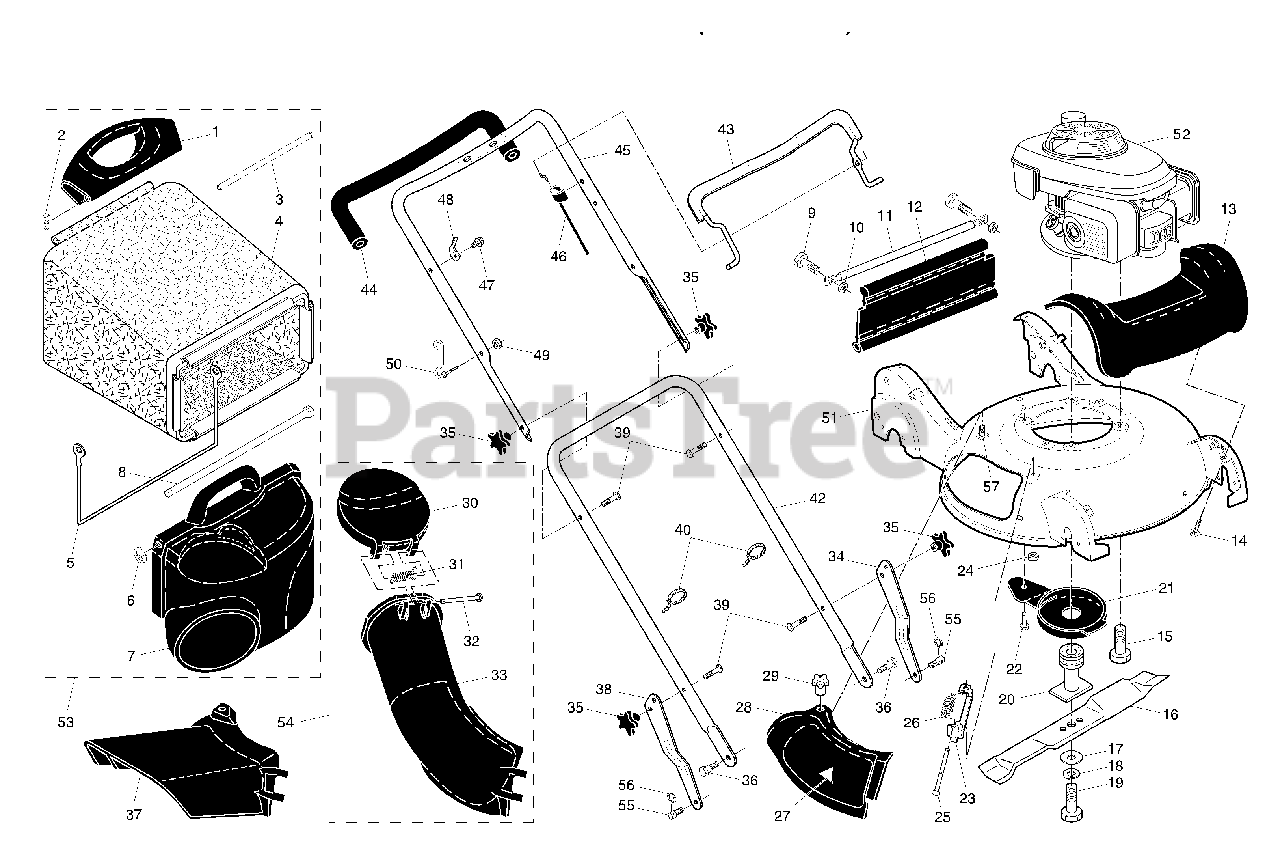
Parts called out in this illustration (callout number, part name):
1	Handle, Grassbag, Rear
2	Hairpin Cotter
3	Rod, Rear Handle, Grassbag
5	Frame, Grassbag
7	Door, Grassbag
8	Rod, Pivot
10	Nut, Hex
11	Tube, Rear Skirt
12	Skirt, Rear
13	Cover, Front
14	Screw, Hex Washer Head
15	Bolt, Engine Mounting
16	Blade, 21"
17	Washer, Hardened
18	Washer, Lock
19	Bolt, Hex Head, Grade 8, 3/8-24 x 2
20	Adapter, Blade
21	Debris Shield
22	Screw, Hex Head, Serrated
23	Mounting Bracket, Mulcher Door
24	Nut, Hex
25	Rod, Hinge
26	Spring, Mulcher Door
27	Decal, Danger
28	Mulcher Door
30	Door, Discharge Chute
31	Spring, Door, Discharge Chute
32	Rod, Door, Discharge Chute
33	Discharge Chute, Plastic
34	Adjustment Bracket, Lower Handle, LH
35	Knob, Star
36	Bolt, Shoulder
37	Deflector, Discharge
38	Adjustment Bracket, Lower Handle, RH
39	Bolt, Handle
40	Wire Tie
42	Handle Assembly, Lower
43	Bail, Control
44	Grip, Foam
45	Handle Assembly, Upper
46	Cable, Engine Zone Control
48	Bracket, Upstop
49	Nut, Hex 1/4-20
50	Rope Guide
51	Kit, Housing
53	Grassbag Assembly, Complete
54	Discharge Chute Assembly, Complete
55	Stud, Shoulder, T45
56	E-Ring, T45
